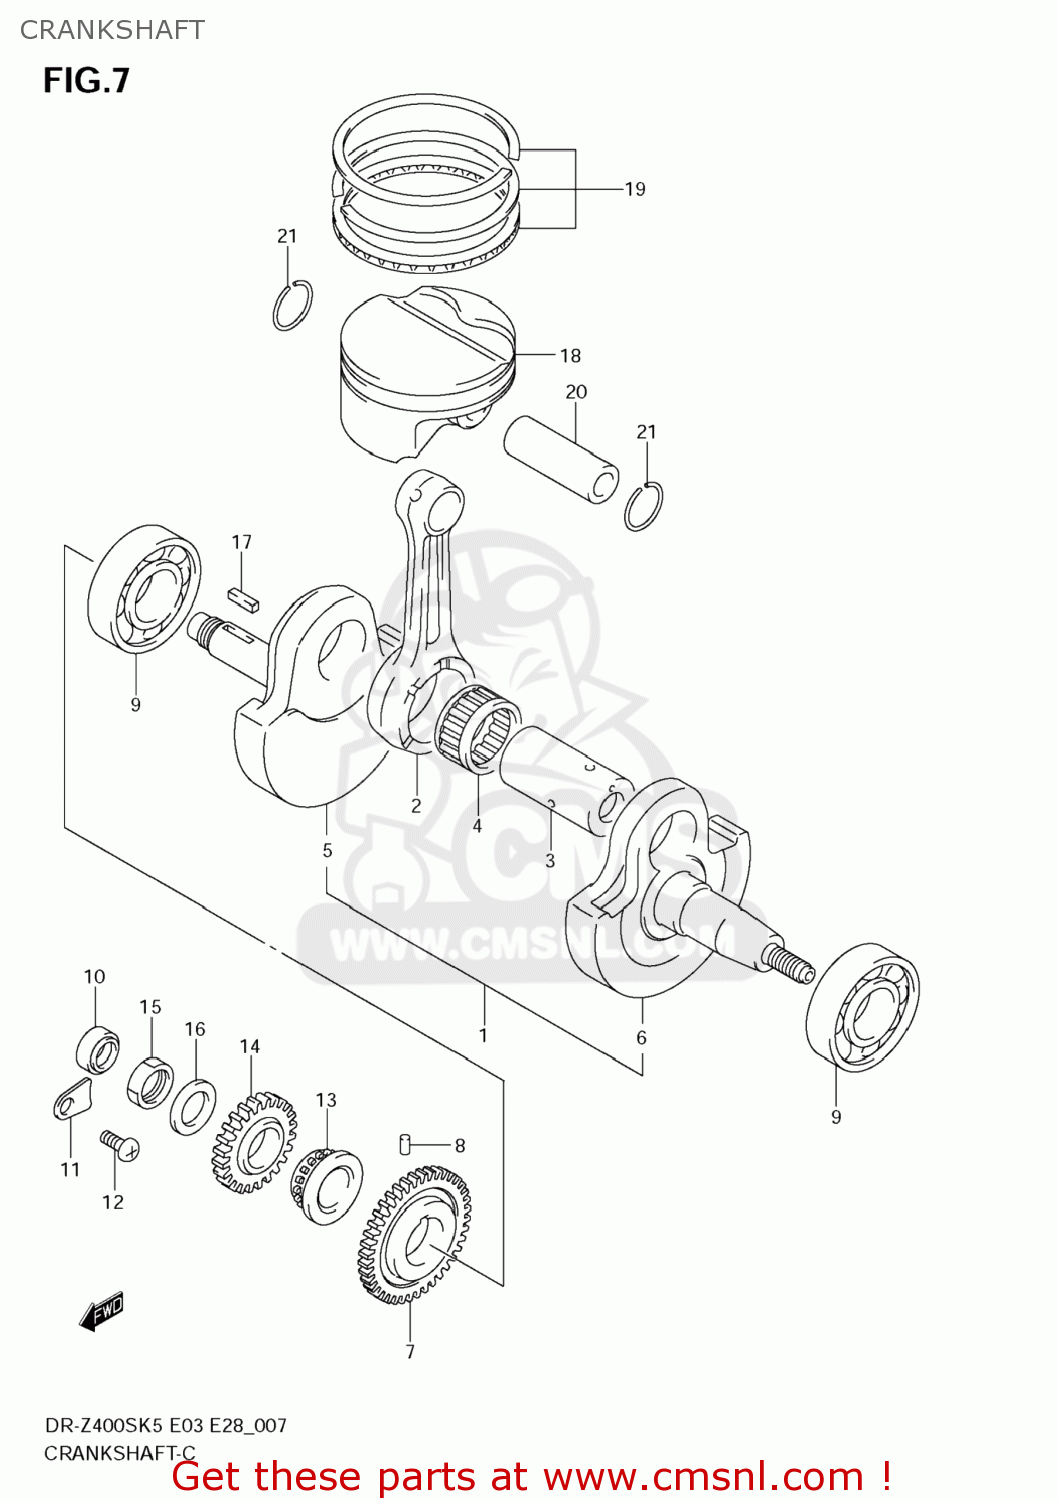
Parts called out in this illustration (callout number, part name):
1	CRANKSHAFT ASS
2	CONNECTING ROD COMP
3	PIN COMP,CRANK
4	BEARING,CRANK PIN
5	CRANKSHAFT,R
6	CRANKSHAFT,L
7	GEAR,CRANK BALANCER DRIVE
8	PIN(5X8)
9	BEARING(30X72X18)
10	SEAL,OIL(14X24X6)
11	RETAINER,BEARING
12	SCREW
13	SPROCKET,CAM CHAIN DRIVE
14	GEAR,PRIMARY DRIVE
15	NUT
16	WASHER
17	KEY
18	PISTON
19	RING SET,PISTON
20	PIN,PISTON
21	CIRCLIP,PISTON PIN
